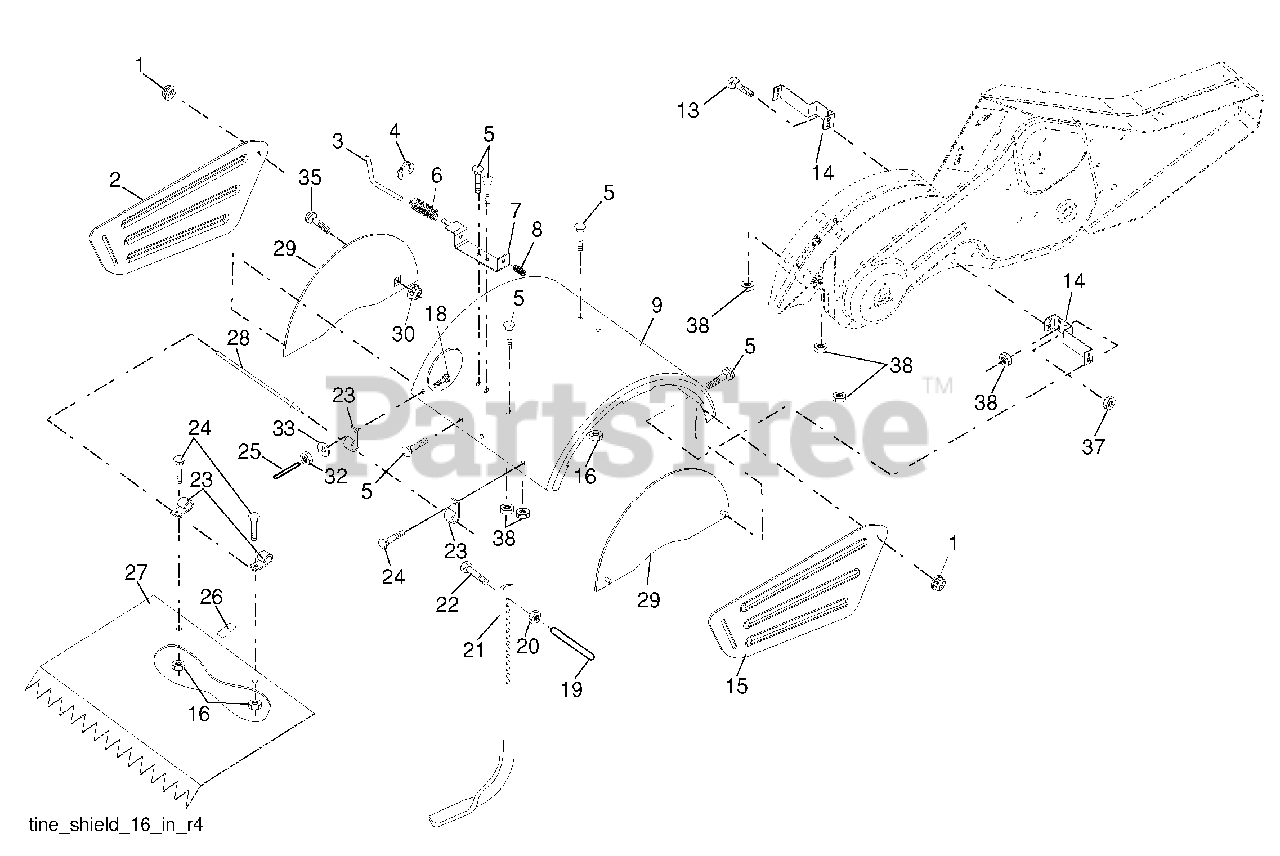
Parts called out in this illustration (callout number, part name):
1	Nut, Lock Hex Flange 5/16-18
2	Shield, Side, Outer L. H.
3	Pin, Stake, Depth
4	Ring, Klip
5	Bolt 5/16-18 x 3/4 ZNC
6	Spring
7	Bracket, Latch
8	Spring, Depth Stake
9	Shield, Tine
13	Bolt, Carriage 5/16-18 x 1-1/4
14	Bracket, Shield Tine
15	Shield, Side, Outer R.H.
16	Nut, Hex Flange 1/4-20 unc
18	Bolt, Carriage 1/4-20 x 1-1/4 Gr. 5
19	Grip
20	Nut, Hex 3/8-16
21	Stake, Depth
22	Bolt, Hex 3/8-16 x 2
23	Hinge
24	Bolt, Carriage 1/4-20 x 1/2 Gr. 5
25	Cap, Vinyl
26	Pad, Idler
27	Shield, Leveling
28	Pin, Hinge
29	Shield, Side
30	Locknut, Flange 5/16-18
32	Nut Fin Hex 1/4-20 unc
33	Washer Lock Hvy Helical 1/4
35	Bolt, Carriage 5/16-18 x 5/8
37	Nut, Lock Hex 5/16-18 unc
38	Nut, Keps 5/16-18 unc
